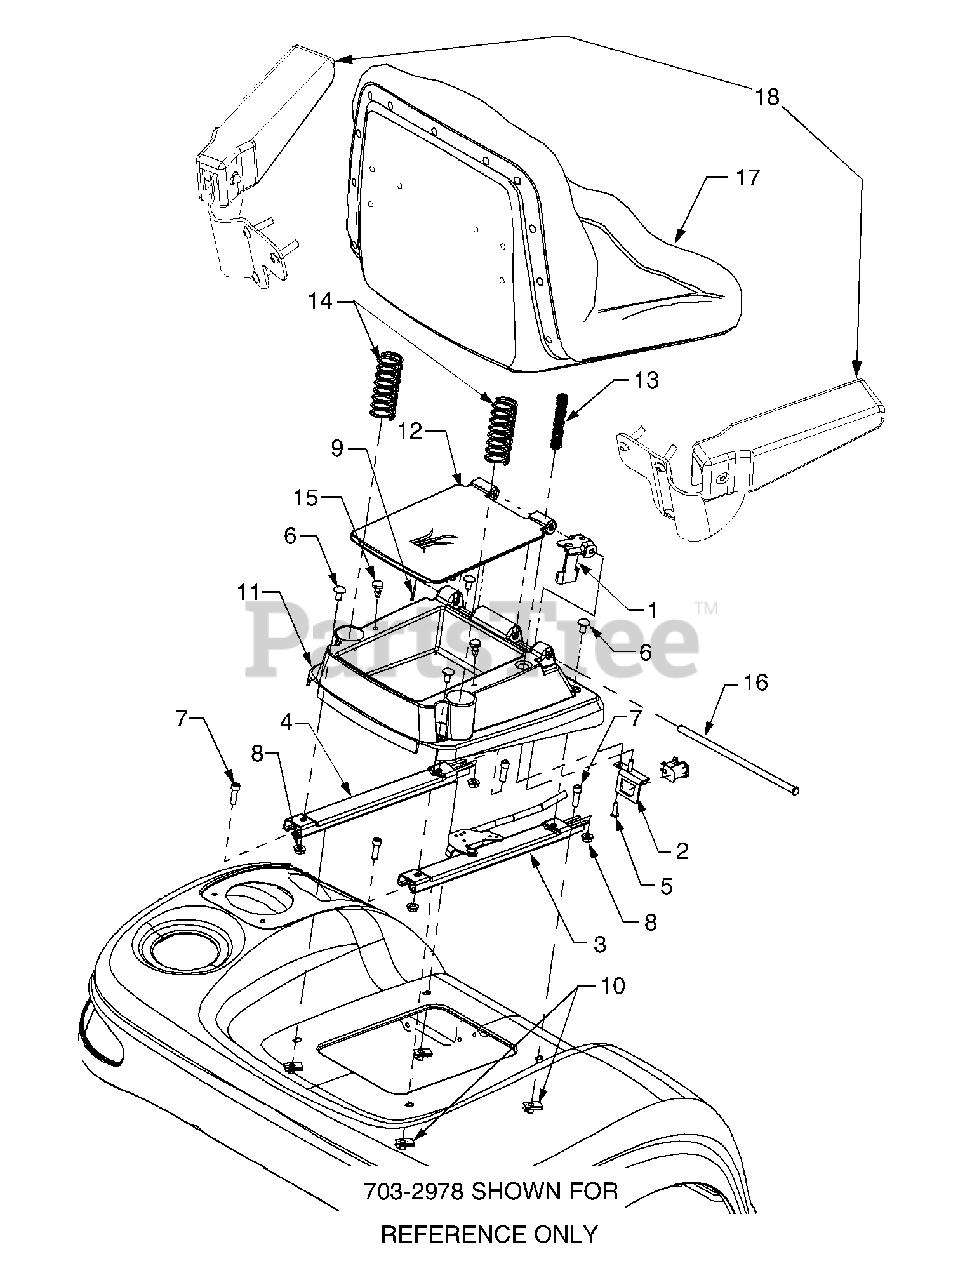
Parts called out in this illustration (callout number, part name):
1	Bracket, Seat Switch
2	Bracket, Switch Mounting
3	Track, Seat, w/Latch
4	Track, Seat, w/o Latch
5	Screw, Pan Torx Hd., #12-14 x.5
6	Carriage Bolt, 5/16-18 x .62
7	Screw, Pan Torx Hd. 5/16-18 x 1.0
8	Nut, Hex Flange Lock, 5/16-18
9	Pin, Cotter, 3/32 x .75
10	Speed Nut, U-Type, 5/16-18
11	Base, Seat
12	Lid, Tlbx
13	Spring, Compression
14	Spring, Compression
15	Bumper
16	Rod, Seat Pivot
17	Seat, High Back
18	Armrest, Seat - Set
